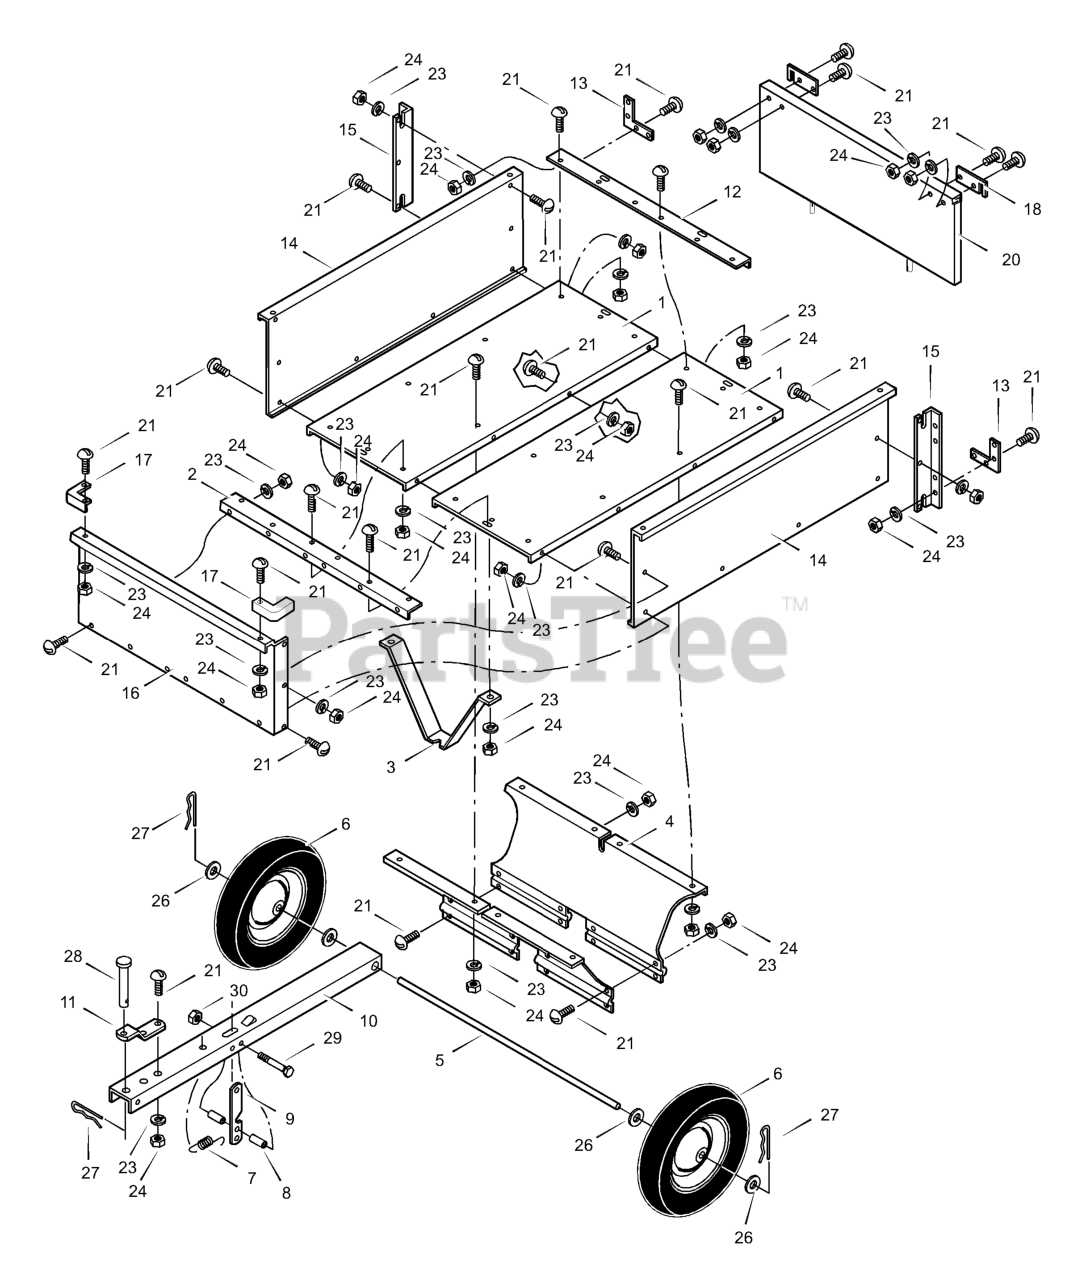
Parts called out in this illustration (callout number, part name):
1	Panel, Bottom
2	Brace, Front Cross
3	Support, Tongue
4	Support, Wheel Axle
5	Axle, Wheel
6	Assembly, Wheel / Tire
7	Spring, Latch
8	Spacer, Latch
9	Latch, Tongue
10	Tongue, Hitch
11	Bracket, Hitch Pin
12	Brace, Rear Cross
13	Bracket, Rear Corner
14	Panel, Side
15	Brace, Rear Corner
16	Panel, Front
17	Brace, Front Corner
18	Latch, Tailgate
20	Tailgate
21	Bolt, Truss Head - M8x16
23	Washer, Lock - 8mm
24	Nut, Hex - 8mm
26	Washer, Flat - 20mm
27	Pin, Cotter - 3mm
28	Pin, Hitch - 12.5x64
29	Bolt, Hex Head - M6x9
30	Nut, Nylon - 6mm
